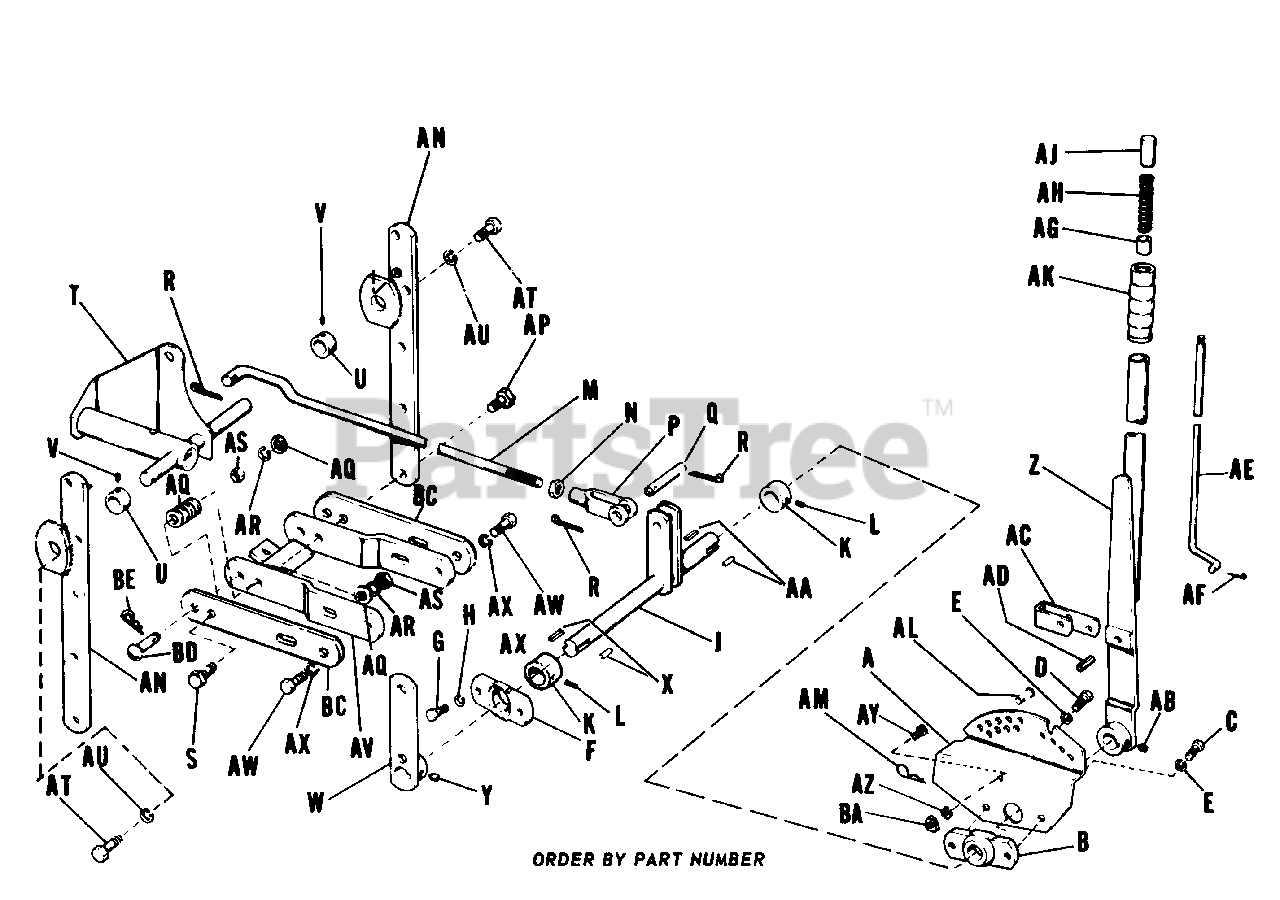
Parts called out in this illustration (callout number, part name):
A	Lift Lever Quadrant
B	Lift Lever Bearing
C	Hex. Cap Screw, 3/8"-16 x 7/8"
D	Hex. Cap Screw, 3/8"-16 x 1-1/4"
E	Lock Washer, 3/8"
F	Lift Lever Bearing
G	Hex. Cap Screw. 3/8"-16 x 7/8"
H	Lock Washer. 3/8"
J	Lift Shaft Assembly
K	Set Collar
L	Set Screw 5/16"-18 x 5/16"
M	Rear Lift Rod
N	Full Hex. Nut, 1/2"-20
P	Adj. Yoke End
R	Cotter Pin, 1/8" x 1"
S	Hex. Cap Screw. 7/16"-14 x 1-3/4"
T	Tiller Lift Assembly
U	Set Collar
V	Set Screw, 5/16"-18 x 5/16"
W	Front Lift Lever Assembly
Y	Set Screw, 5/16"-18 x 1/4"
Z	Lift Lever Assembly
AB	Set Screw, 5/16"-18 x 1/4"
AC	Lift Lever Latch
AE	Latch Rod
AF	Cotter Pin, 3/32" x 3/4"
AJ	Thumb Button
AK	Handle Grip
AM	Spring Clip
AN	Arm Assembly
AP	Hex. Capscrew, 7/16"-14 x 1-1/2"
AQ	Plain Washer, 3/8"
AR	Lock Washer, 3/8"
AS	Full Hex. Nut, 7/16"
AT	Hex. Cap Screw, 7/16"-14 x 1"
AU	Lock Washer, 7/16"
AV	Draw Bar Assembly
AW	Hex. Cap Screw, 7/16"-14 x 1-1/4"
AX	Lock Washer, 7/16"
AY	Hex Capscrew, 1/4-20 x 5/8" lg.
AZ	Lock Washer, 1/4"
BA	Hex Nut 1/4-20
BB	Hex. Cap Screw, 5/16"-18 x 7/8"
BD	Round Head Pin
BE	Spring Clip
